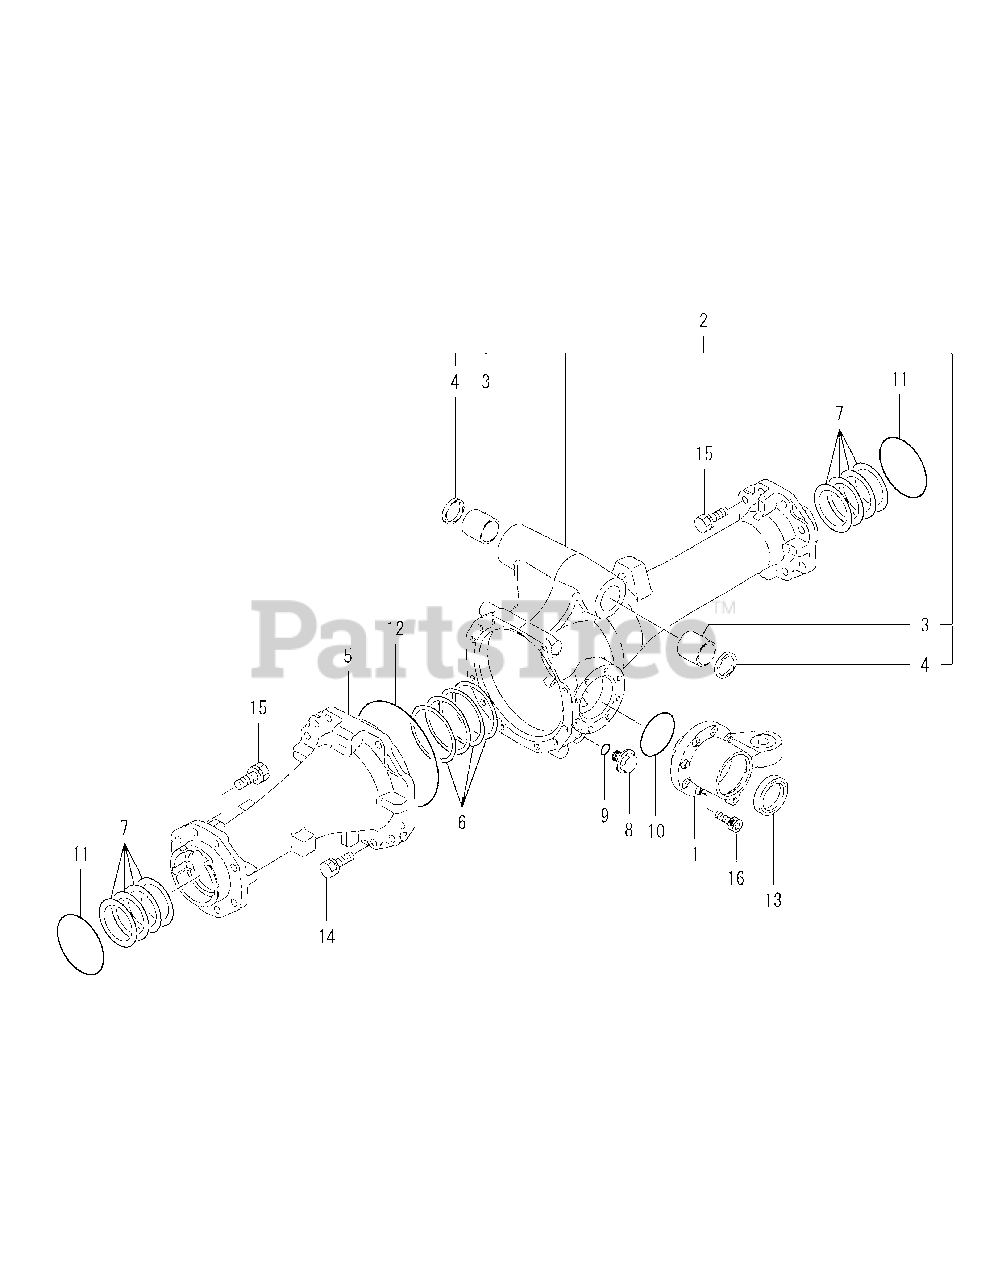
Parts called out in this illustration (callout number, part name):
1	RETAINER, BEARING
2	AXLE HOUSING RH.ASSY
4	SEAL VB 354105, OIL
5	HOUSING, FRONT AXLE
7	SHIM SET, PINION
9	O-RING 1A P-16.0
10	O-RING 1A G70.0,NBR
11	O-RING 1A G-100.0
12	O-RING 1A G-170.0
13	SEAL TC 456209, OIL
14	BOLT W/WASHER M12X30
15	BOLT W/WASHER M12X30
